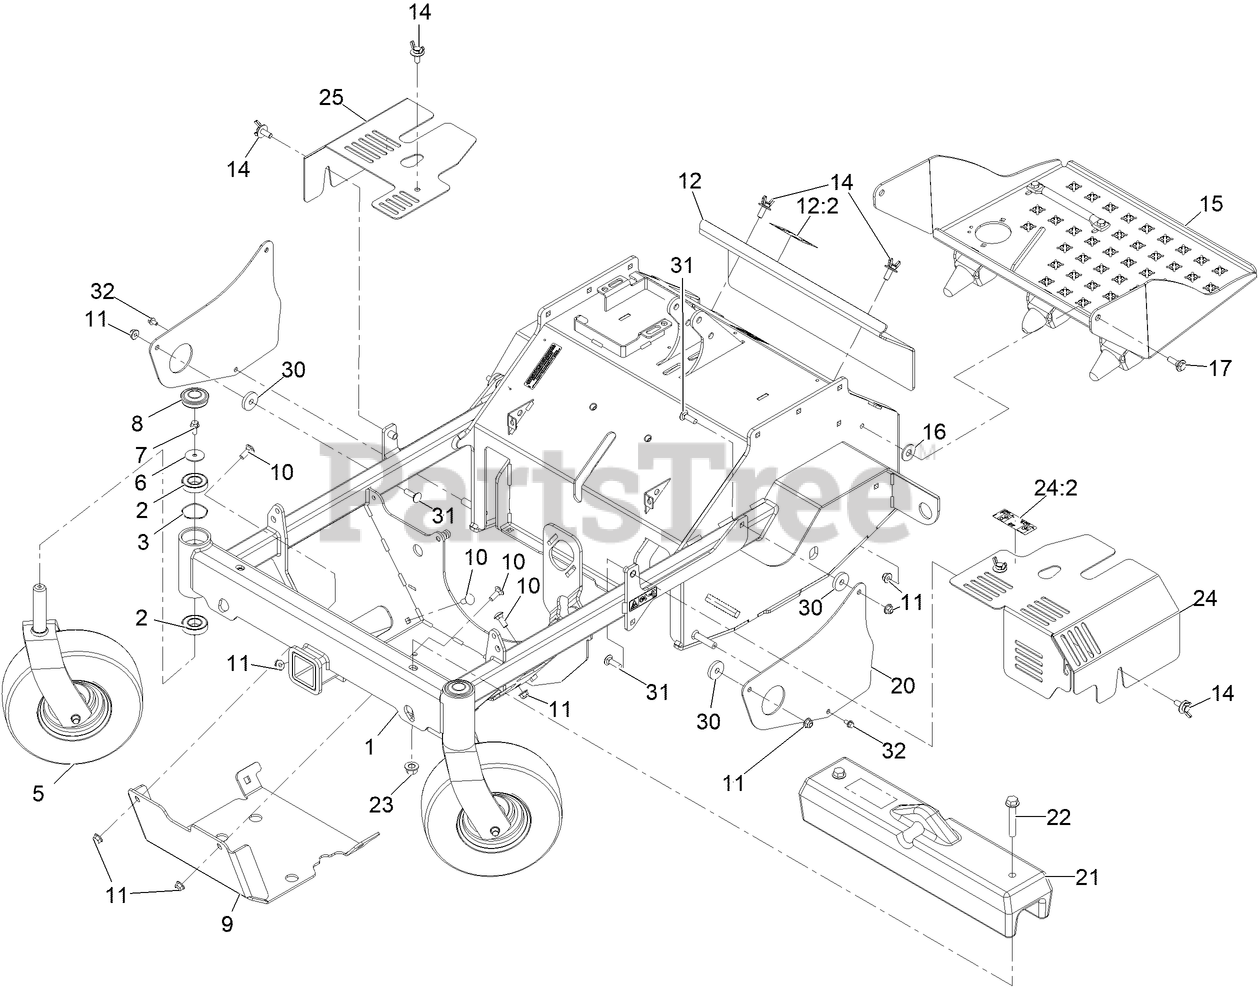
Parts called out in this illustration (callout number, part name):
1	Main Frame ASM
2	BEARING-BALL
5	Front Caster ASM
6	WASHER-FLAT
7	SCREW-HHF
8	CAP-GREASE
9	GUARD-ENGINE
10	BOLT-CARR
11	NUT-HF, NI
12	ACCESS COVER ASM
12:2	DECAL-OPERATION, TINE GRO
14	Screw-Sems (3/8-16 X 1)
15	PLATFORM ASM
16	WASHER-FLAT
17	SCREW-SHOULDER, HWH
20	Guard-Chain
21	WEIGHT-FRONT
22	SCREW-HF
23	Nut-Lock 1/2-13
24	HYDRO-COVER
24:2	DECAL-RELEASE, DRIVE
25	COVER-HYDRO
30	WASHER-CLUTCH
31	BOLT-CARR
32	SCREW-HHF
